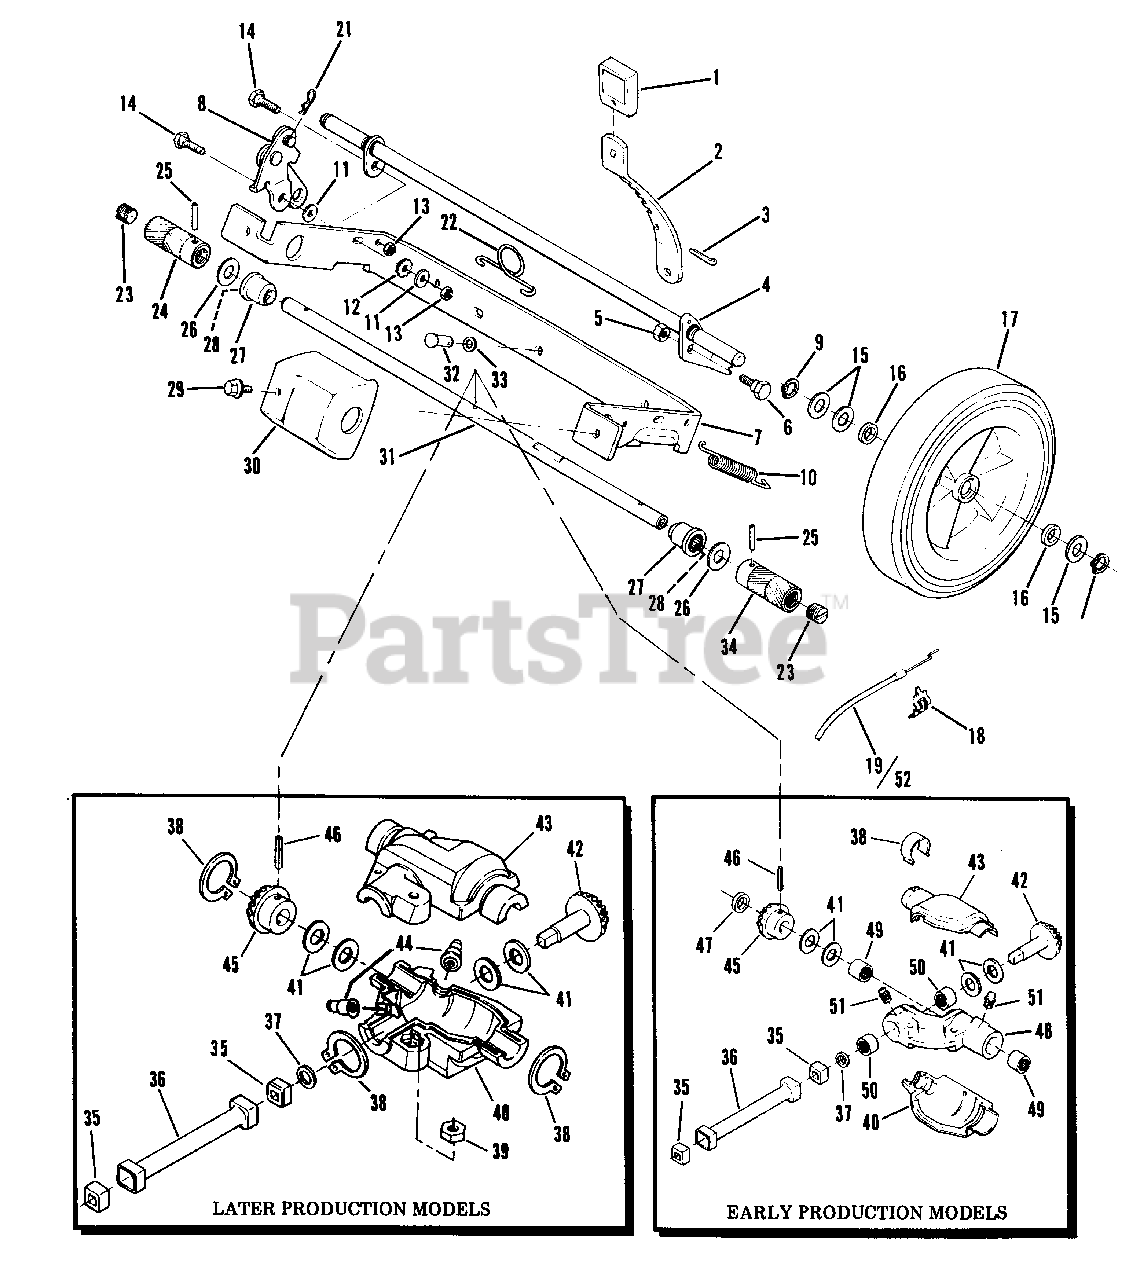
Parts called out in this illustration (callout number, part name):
1	Knob-Rear Height ht. Adjustment Lever
2	Lever-Rear Height Adjust
3	Cotter Pin
4	Axle Assembly
5	Locknut
6	Bolt-Shoulder
7	Bracket-21" Axle
8	Clutch Assembly
9	Retaining Ring
10	Spring
11	Washer
12	Lockwasher
13	Stop Nut
14	Bolt-Shoulder
15	Washer
16	Washer-Felt
17	Wheel-Rear
18	Clip
19	Cable-Interlock-Manual
20	Retaining Ring
21	Lock Pin
22	Spring-Height Adjust
23	Plug
24	Drive Roller-R.H.
25	Pin-Roll
26	Washer
27	Sleeve & Bearing Assembly
28	Needle Bearing
29	Screw-Sems
30	Guard-Roller
31	Shaft
32	Pin-Rear Height Adjust Lever
33	Spring Washer
34	Drive Roller-L.H.
35	Bushing
36	Tube-Drive
37	"O" Ring-Spacer
38	Clamp
40	Cover-Gear Bottom
41	Washer
42	Gear-Drive
43	Cover-Gear Top
45	Gear Driven
46	Pin-Roll
47	Washer-Felt
48	Bracket & Bearing Assembly
49	Needle Bearing
50	Needle Bearing
51	Zerk Fitting
52	Cable-Interlock-Electric
